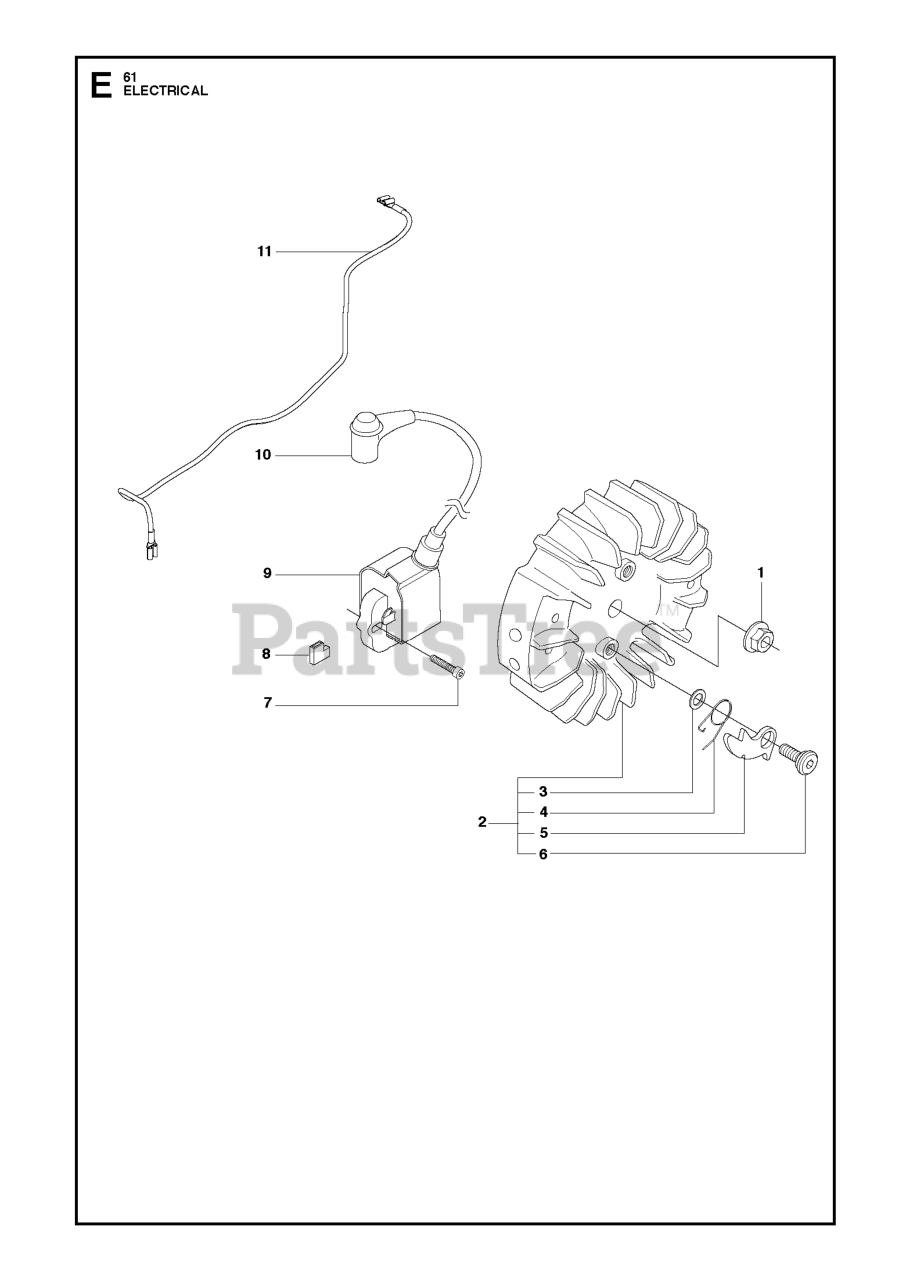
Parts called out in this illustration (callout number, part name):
1	NUT W/ WASHER
6	SCREW M5X14
8	INSULATING CAP
9	IGNITION MODULE
10	SPARK PLUG CONN. KIT
11	SHORTING LEAD
